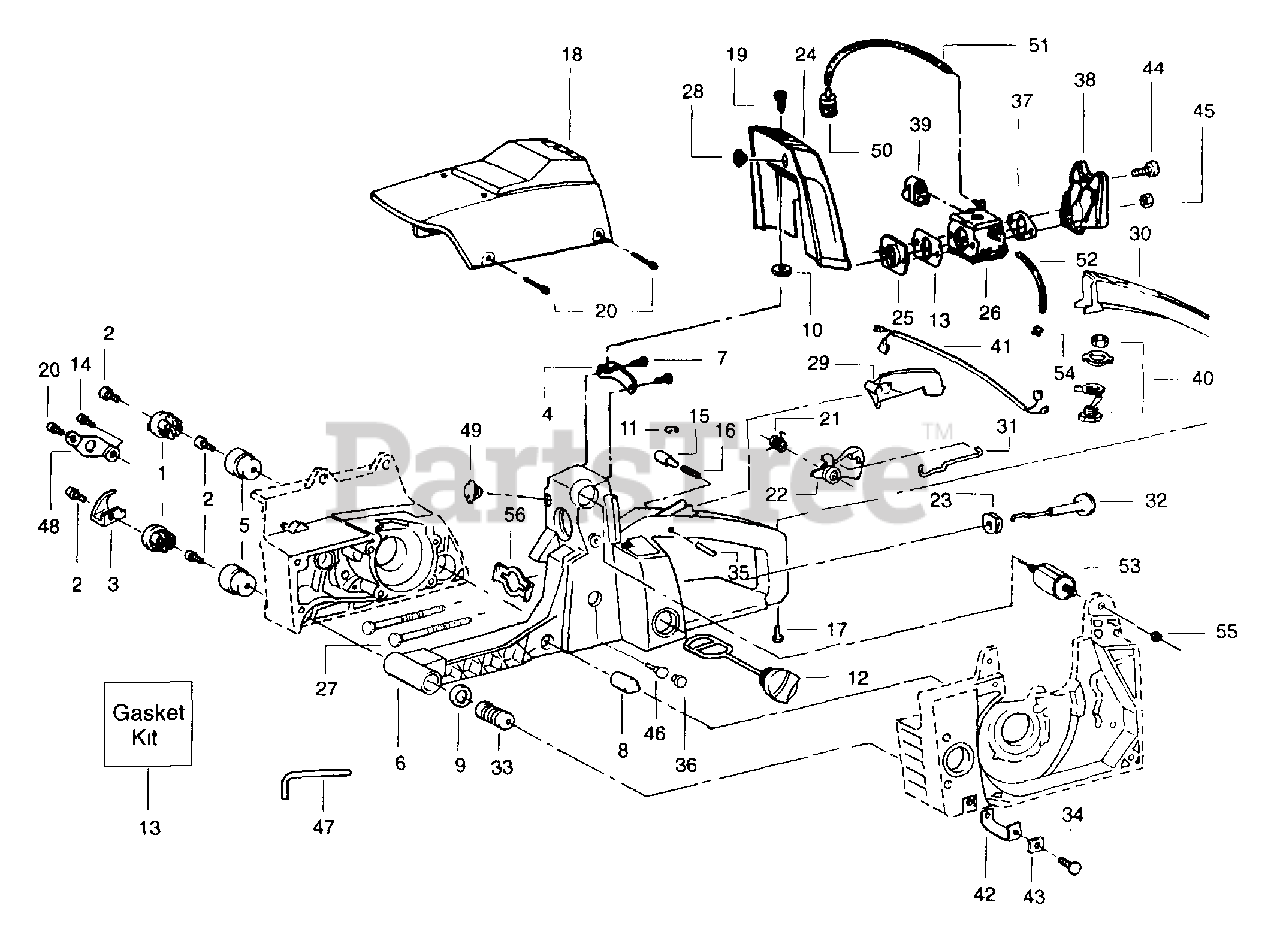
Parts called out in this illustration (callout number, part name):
1	Retainer - Chain Catcher
3	Chain Catcher
4	Bracket - Carb Cover Mount
5	Isolator - Lower
6	Rear Handle & Fuel Tank Kit
8	Bumper - Isolator
10	Retainer - Screw
11	"C" Clip - Throttle Lock
12	Fuel Cap Ass'y.
13	Gasket Kit
15	Throttle Lock Button
16	Throttle Spring
18	Cylinder Shield Kit w/reflector
21	Trigger Latch Spring
22	Throttle Trigger
23	Grommet - Choke Rod
24	Carb. Cover
25	Bracket - Intake Manifold
26	Carburetor
27	Carb. Mounting Stud
28	Bumper - Carb. Cover
29	Throttle Lockout
30	Rear Handle Cover
31	Throttle Wire
32	Choke Rod Ass'y
33	Isolator Kit
35	Dowel Pin - Trigger
36	Plug - Bronze Vent
37	Plate Air Filter
38	Air Filter Ass'y
39	Carb. Grommet
40	Switch Kit
41	Lead Wire Ass'y
42	AV Strap
43	Strap Retainer Plate
44	Screw
45	Carb. Nut
46	Check Valve
47	Hex Wrench 5/32
48	Bracket - Retainer
50	Fuel Pick-up Ass'y
51	Fuel Line Kit
52	Line Kit Bulk 530008133
52	Bulk Line
53	Mount - Cylindrical
54	Clamp - Impulse
56	Bracket - Carb Stud
